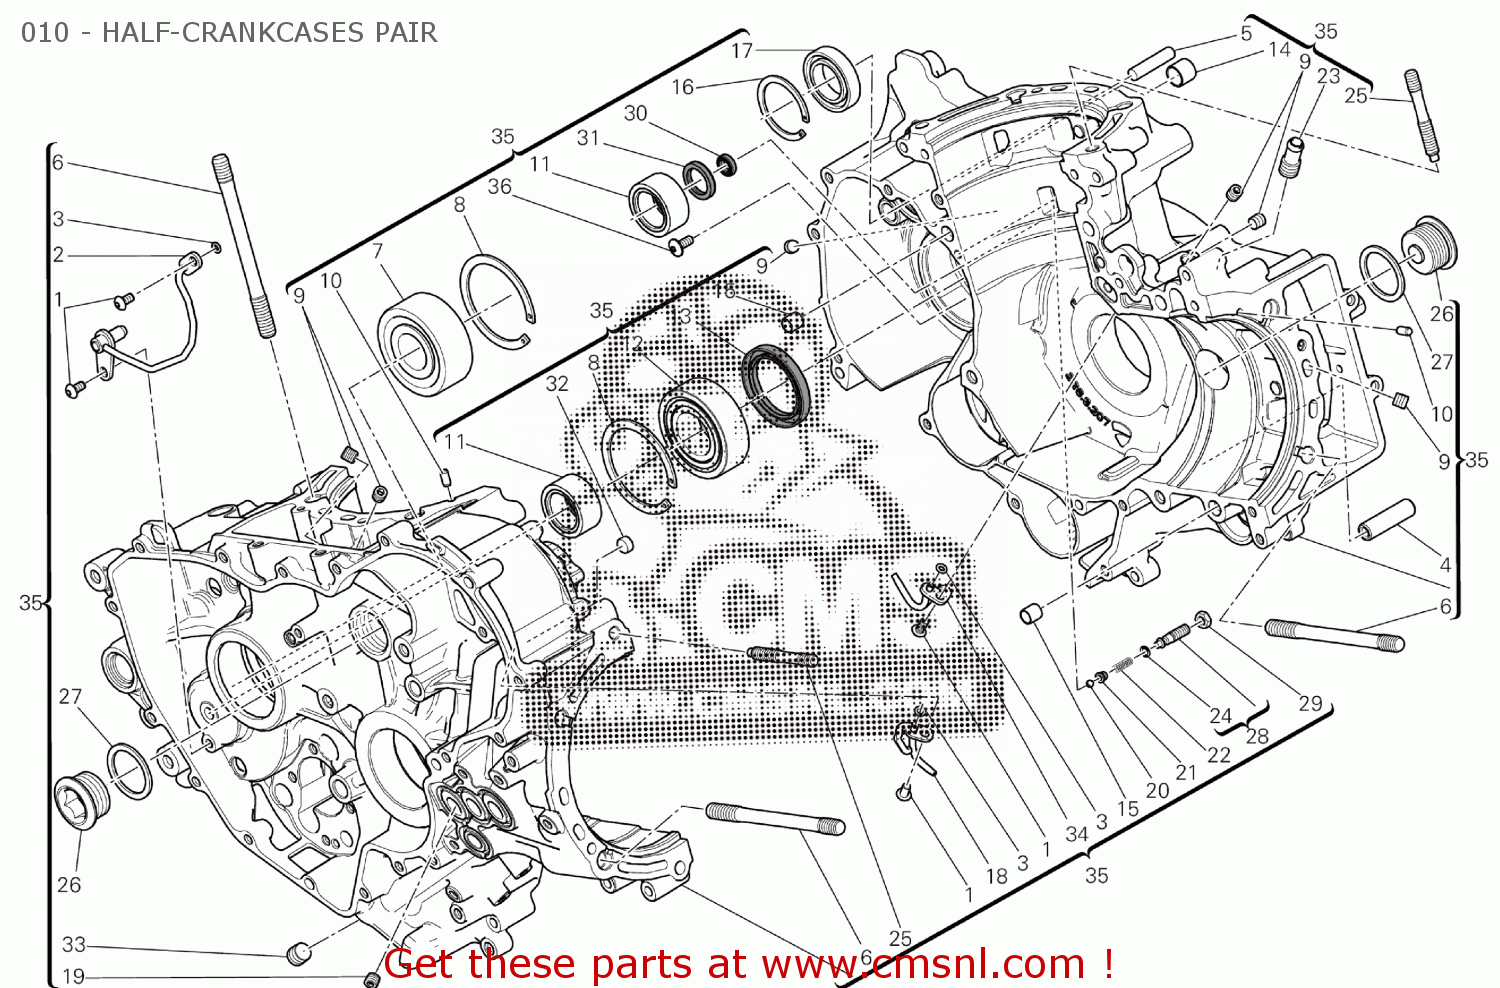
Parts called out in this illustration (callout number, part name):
1	SCREW TBEI M5X10
2	HOSE, OIL
3	O-RING 3.68X1.78
4	STARTER REDUCTION SHAFT
5	PIN
6	STUD BOLT FASTENING HEAD CYLINDER
7	BEARING
8	SNAP RING
9	THREADED DOWEL
10	PIN M5X10
11	BEARING
12	BEARING, NEEDLE
13	SEAL, OIL 40X55X7
14	BUSH
15	LOCAT. DOWEL
16	CIRCLIP
17	BEARING 25X42X9
18	JET RH
19	SPECIAL SCREW
20	BALL
21	PLATE
22	SPRING
23	UNION RETURN
24	O-RING
25	STUD BOLT FASTENING HEAD CYLINDER
26	PLUG
27	WASHER
28	SCREW
29	NUT
30	SEAL RING
31	SEAL, OIL 17X25X4
32	PLUG 10 MM
33	THREADED DOWEL
34	JET LH
35	COMPLETE HALF-CRANKCASES PAIR
36	SCREW TBEIF M6X10
